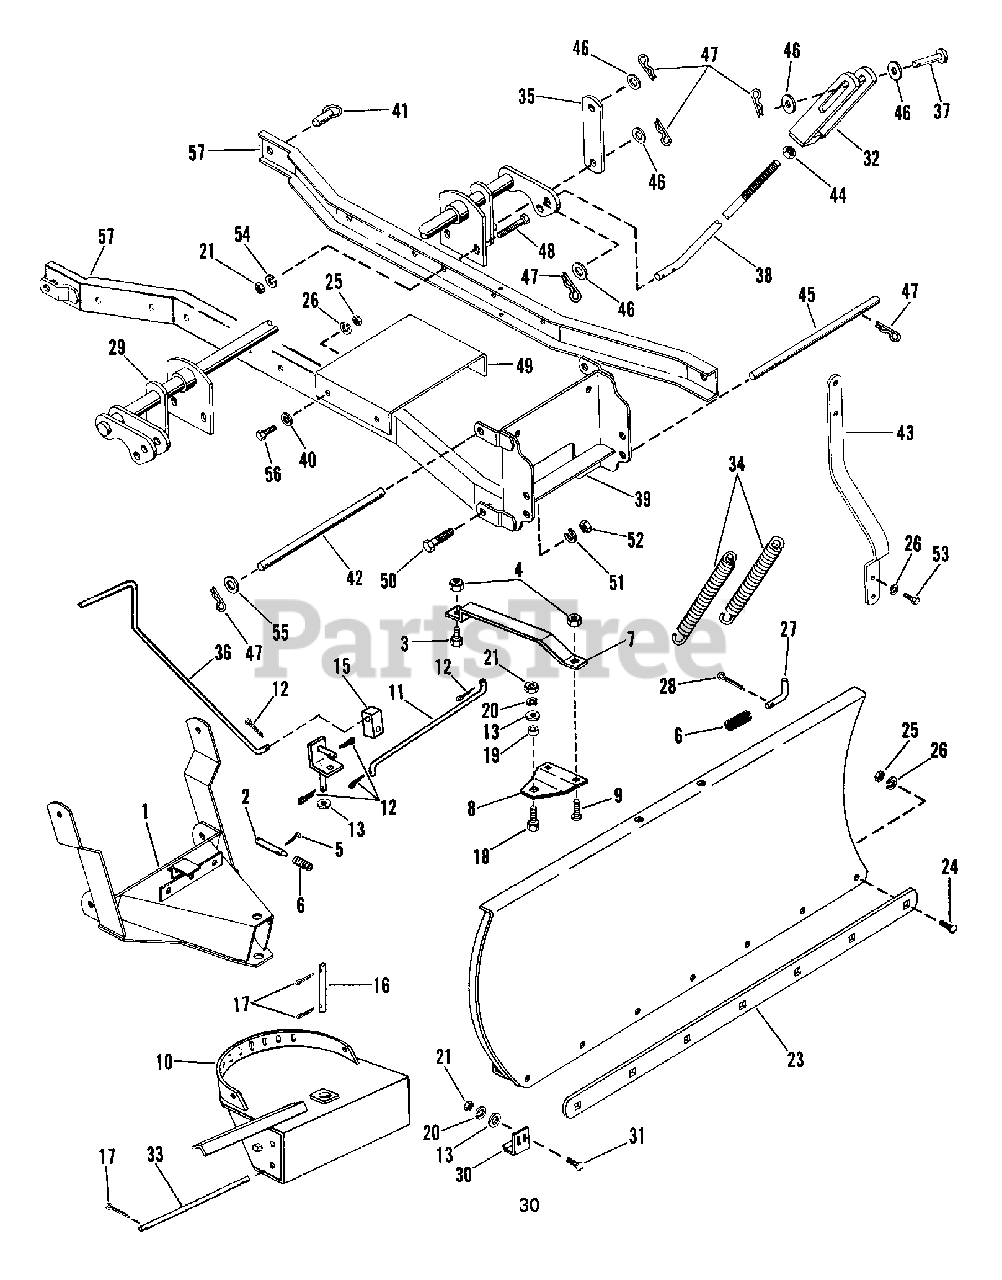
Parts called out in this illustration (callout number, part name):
2	LATCH PIN
3	BLT-HEX .31-18X1.25 PL GR2
4	NUT-LK .312-18 GR A PL
5	PIN-COTR .12X1.0 PL
6	SG-COMP .080X.85X1.44
8	PIVOT PLATE
9	BLT-RDHDSQNK .31-18X.75 SHT PL
10	SUPPORT
12	PIN-COTR .12X.75 PL
13	WSHR-FL-STL .438X1.0X.083 PL
15	UNIVERSAL BLOCK JOINT
17	PIN-COTR .18X1.0 PL
18	BLT-HEX .38-16X1.00 PL
19	SPACER .406X.749X.162
20	WSHR-LK .375X.094 MED PL
21	NUT-HEX .375-16
22	BLADE 42 INCH
23	WEAR PLATE
24	BLT-RDHDSQNK .31-18X1.00 PL
25	NUT-HEX .312-18
26	WSHR-LK .312X.097 PL HVY
27	JACK PIN
28	PIN-COTR .12X1.0 PL
29	LIFT BELLCRANK WELDMENT
30	SKID SHOE
31	BLT-RDHDSQNK .38-16X1.0 PL
32	LIFT CLEVIS WELDMENT
34	SG-TENS .187X1.50X9.94 WLD 40
35	CONNECTING LINK
37	PIN-CLEV .494X1.94 YWZC
38	LIFT ROD
39	MOUNTING BRACKET
40	WSHR-FL-STL .323X.625X.062 PL
41	HITCH PIN
42	PIVOT ROD
43	CHUTE CRANK SUPPORT
44	NUT-JAM .50-13 PL
45	PIVOT ROD
46	WSHR-FL-STL .531X1.062X.095 PL
47	PIN-HAIR INT .09X.188 PL
48	BLT-HEX .38-16X1.00 PL GR5
49	STIFFENER BRACKET
50	BLT-HEX .62-11X1.50 PL GR2
51	WSHR-LK .625X.156 MED PL
52	NUT-HEX .625-11
53	BLT-HEX .31-18X1.00 PL GR 2
54	WSHR-LK .375X.115 HVY PL
55	WSHR-FL-STL.656X1.312X.095 PL
56	BLT-HEX .31-18X.75 PL GR5
57	CHANNEL WELDMENT
